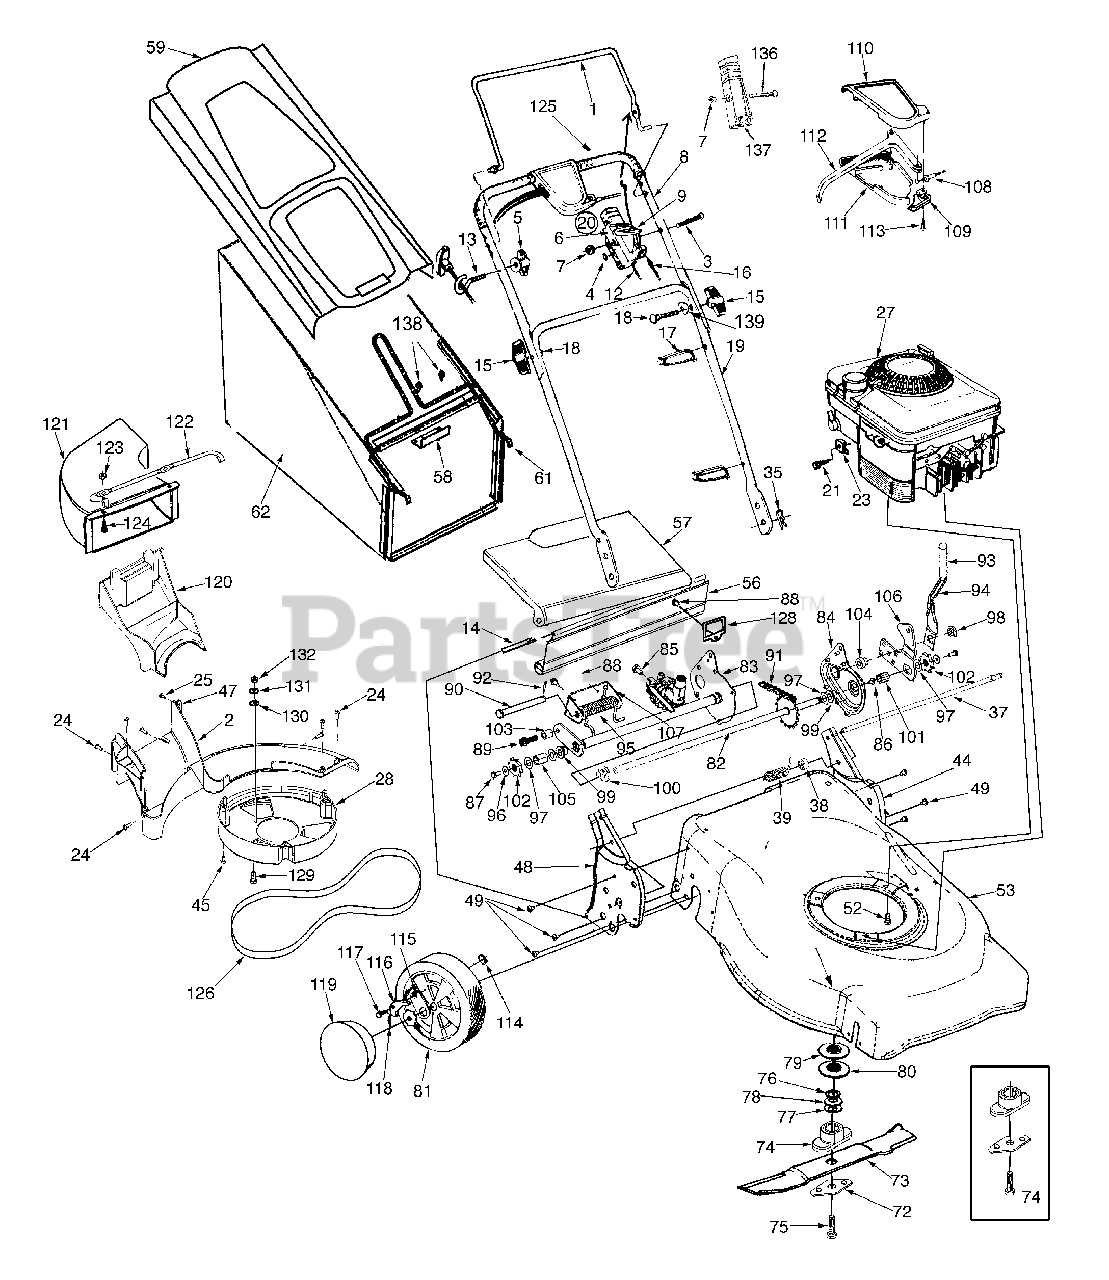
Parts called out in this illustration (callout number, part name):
1	Control Handle Ass'y
2	Baffle
3	Oval C-Sunk Mach-Screw
4	Spring Washer .66" ID
5	Handle Knob 1/4-20 Thd.
6	Throttle Body
7	Hex L-Nut 1/4-20
9	Throttle Lever
12	Throttle Control Wire - 47"
13	Rope Guide
14	Wire-47" Lg.
15	Hand Knob
16	Control Cable-45"
17	Cable Tie
18	Cr.Hd. Bolt 5 / 16-18 x 2" Lg.
20	Throttle Assy.
21	Hex Self-Tap Scr. #10-32 x.62"
23	Cable Clamp
24	Screw H.L. 12-24
25	Screw Mach. B Tapp.
28	Belt Cover
35	Int. Cotter Pin 5/15" Dia.
37	Pivot Rod
38	Spacer .385 I.D.
39	Torsion Spring L.H.
47	U-Nut
52	Hex L-Wash. Hd. Scr. 3/8-16 x 1"
53	21" Deck
56	Rear Flap 17.77 Lg.
62	Grass Bag - Black
72	Blade Bell Support
73	21" Mulching Blade w/Star
74	Blade Adapter
75	Hex Bolt 3/8-24 x 2.5 Lg.
76	Spacer
77	Fl. Wash. .885 x 1.85 x .06
78	Spr. Wash. .890 x .7 x .04
79	Pulley Half - Upper
80	Pulley Half - Lower
81	Wheel Assembly
82	Axle Assy: RR
86	Scr. TT 1/4-20
87	Hx Cap Screw 1/4-20
88	Hex Washer Screw 1/4-20 x .625
89	Scr 3/8 - 16 x 1.25
90	Pin - Clv. .500 Dia.x.4.62 Lg.
91	Chain:Endless 48:.500P x 22 Lg.
92	Pin-Cotter .125 O.D. x .75
93	Grip-Foam
94	Spring Lever
95	Torsion Spring
96	Bell Washer .265 x .75 x .062
97	Wash.Flat.508 I.D. x 1.0 O.D.
98	Nut - Shoulder .625 x .165 Lg.
99	Bearing-Flg Hex
100	Bearing-Flg. Hex
101	Bearing-Sleeve
102	Ratchet Wheel
103	Spacer - .385 x .625 x .700
104	Spacer-Shld. .385 I.D.x .715 Lg.
105	Spacer Slv. .520 I.D. x .950 Lg.
109	Mounting Cap
110	Control Cover - Upper
111	Control Cover - Lower
112	Lever
113	Screw #10-16 x.625
114	Weld Top L. 1/4-20
115	Pawl Plate
117	Shldr. Scr. .340 x .285
118	Spring, Ratchet
119	Hub Cap
120	Mulch Plug
121	Chute Deflector
122	Chute Mounting Rod
123	Hex-L-Nut 1/4-20 thd.
124	Mach. Scr. 1/4-20
125	Foam Grip
126	Belt
130	Lockwasher 1/4" Reg.
131	Fl. Wash. .271 x .630 x .065
132	Nut 1/4-20
136	Scr. 1/4-20:1.31 Lg.
137	Housing (w/o Throttle)
138	Hex Washer Screw 1/4-20 x.625
